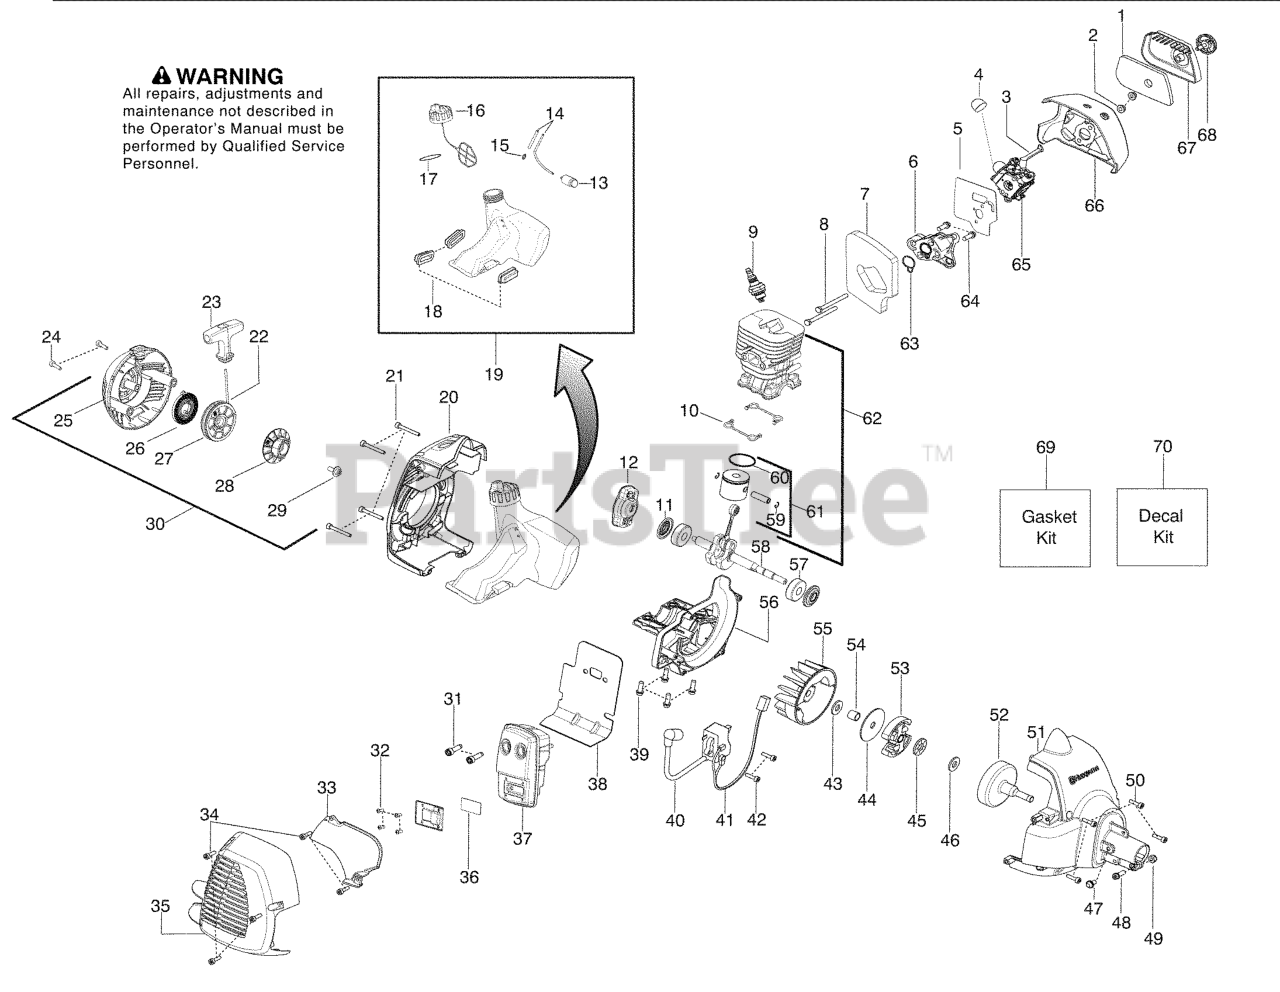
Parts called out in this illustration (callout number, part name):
2	Nut-Carb. Screw
3	Lever - Choke
4	Bulb-Purge
5	Kit-Carb. Gasket
6	Adaptor-Carb.
7	Foam-Gasket (kit)
9	Plug-Spark (RCJ-8Y)
10	Seal-Cylinder (kit)
11	Seal-Crankshaft (kit)
12	Assy-Starter Pawl
13	Assy-Fuel Filter
14	Kit-Fuel Line
15	Fitting-Fuel line
16	Assy-Cap w/ret.
17	O-ring - Fuel Cap (kit)
18	Isolator-Fuel Tank
19	Kit-Fuel Tank Assy.
20	Shroud-Rear
22	Kit-Rope
23	Handle-Starter
25	Hsg.-Starter w/eyelet
26	Kit-Starter Spring
27	Kit-Starter Pulley
28	Pulley-Driver
30	Assy-Starter Hsg.
31	Bolt-Muffler
32	Screw
33	Shield-Heat
35	Guard-Muffler
36	Kit-Spark
37	Assy-Muffler
38	Gasket-Paper Met.(kit)
41	Assy-Leadwire
44	Washer-Clutch
45	Bearing - Thrust
46	Washer - Thrust
51	Assy-Fan Housing
52	Assy-Clutch Drum
53	Kit-Clutch Assy.
56	Crankcase-Cast
58	Assy-Crankshaft
59	Retainer-Piston Pin
60	Ring-Piston
61	Kit-Piston
62	Kit-Piston/Cyl.
63	Seal-adaptor (kit)
65	Kit-Carb.
66	Airbox
67	Cover-Air Box
69	Kit-Gasket
